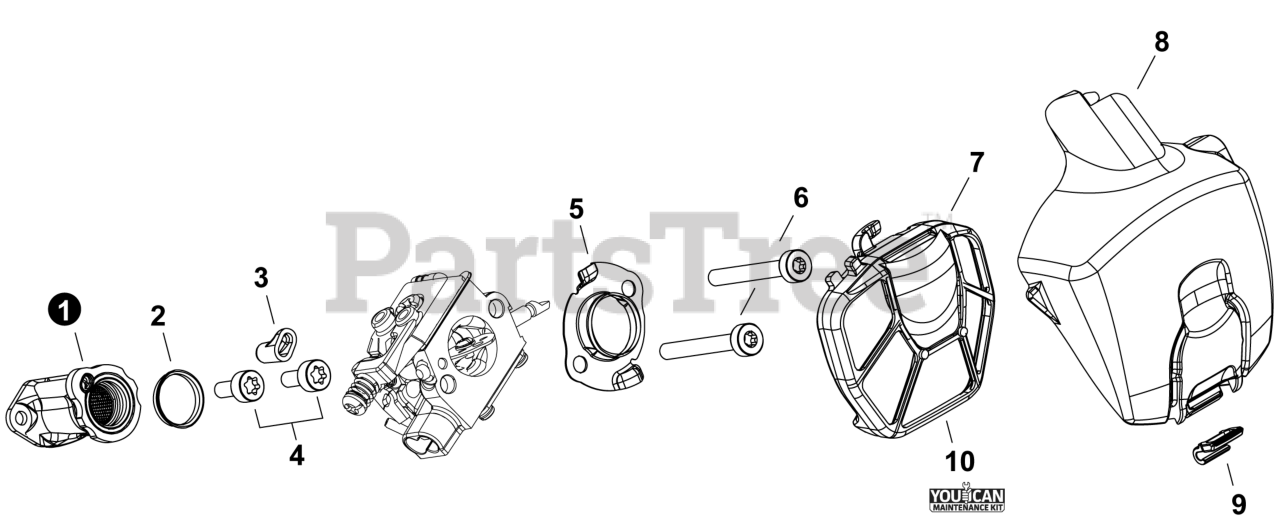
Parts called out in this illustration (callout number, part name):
1	BELLOWS, INTAKE
2	COLLAR 14
3	COLLAR 3
4	BOLT, TORX 4x10
5	ELBOW, CARBURETOR
6	BOLT, TORX 5x40
7	FILTER ASSY, AIR - NYLON MESH
8	COVER, AIR FILTER
9	RETAINER, AIR FILTER
10	TUNE-UP KIT - YOUCANT
